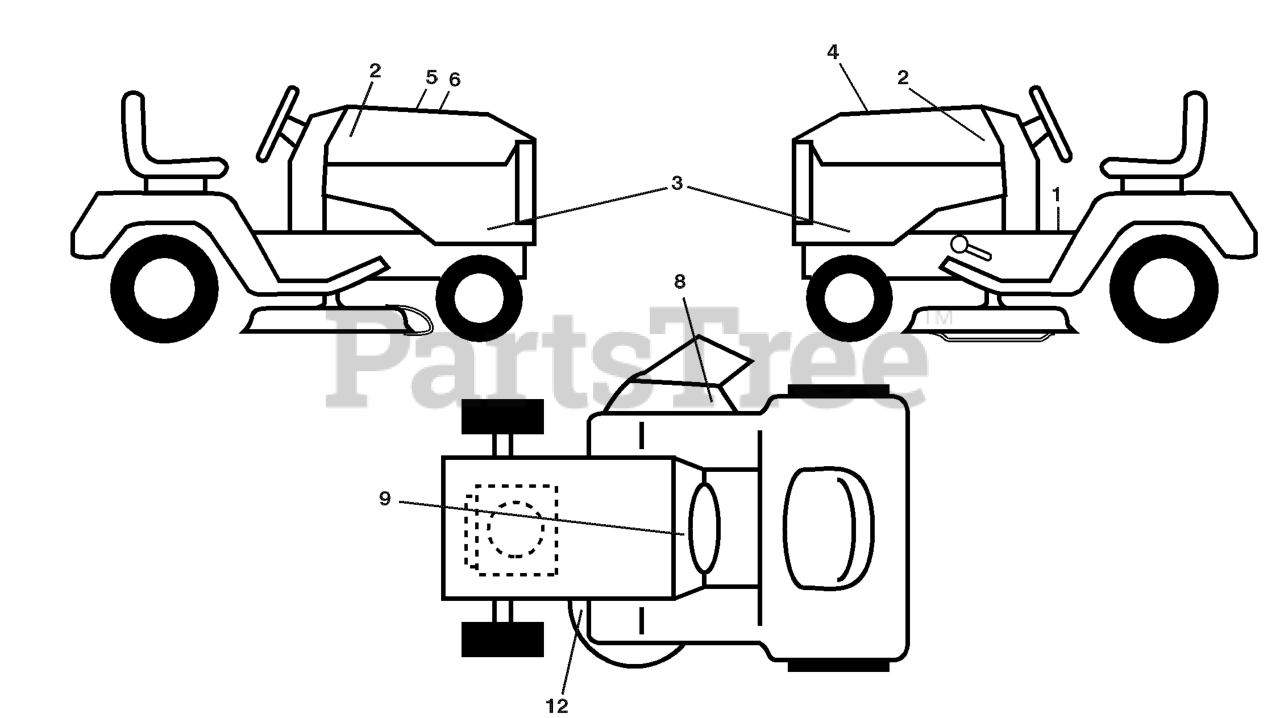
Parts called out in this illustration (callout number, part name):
1	DECAL.FENDER.WARNING.ENG
2	EMBLEM.HOOD.HUSQ.DEALER
3	DECAL.SDPNL.2348LS.ENDUR.HUSQ
4	DECAL.ENG.BSM44.23.ENDUR.27817
5	DECAL HOOD CUST. RESP.
6	DECAL.RPL.M44.ENDUE.TLW.48EK46
8	DECAL.WARN.KEEP.HAND.AWAY
9	DECAL BTRY SYMBOLS
12	DECAL.MOWER.SCH.48/54
